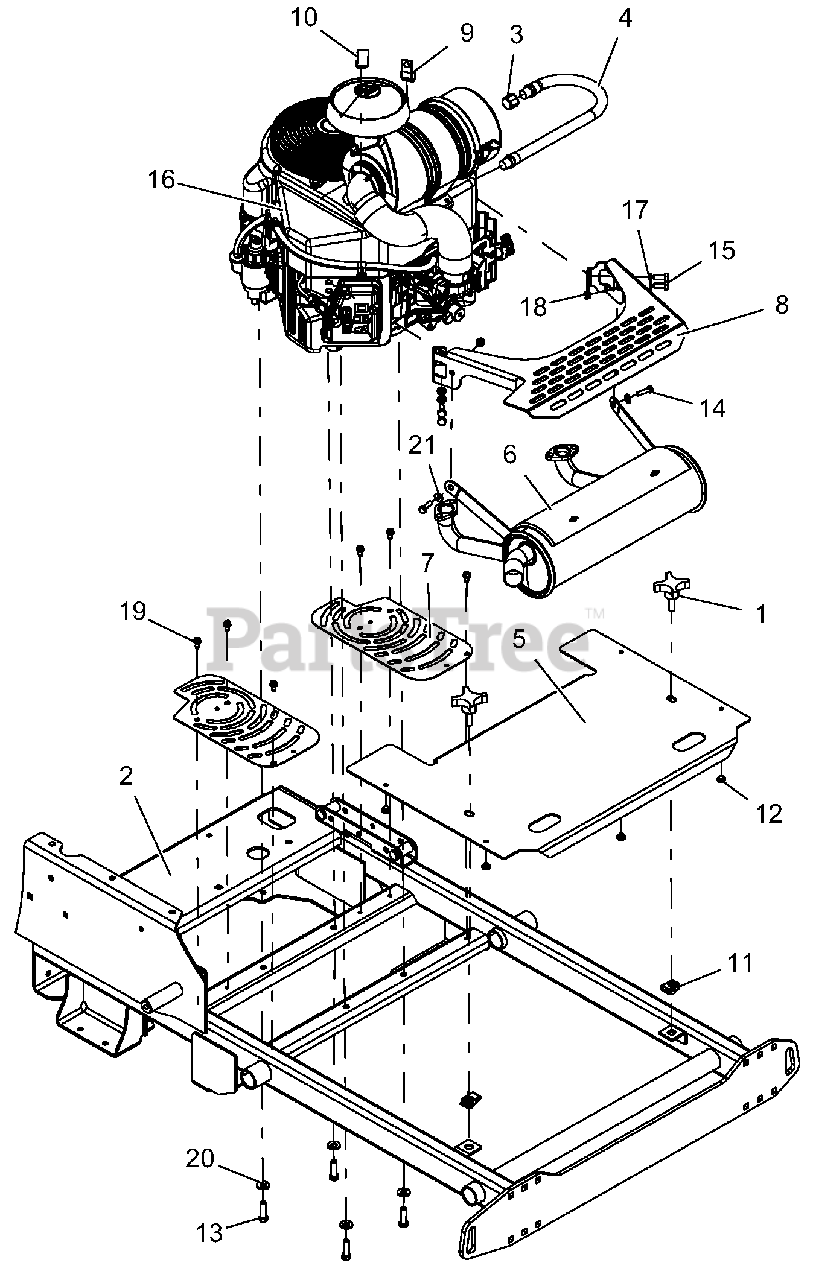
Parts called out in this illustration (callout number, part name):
1	KNOB, 3/8 x 1.25 - 4 PRONG
2	WLDMT, FRAME PROSTANCE
3	PIPE, CAP 3/8 NPT FEMALE
4	DRAIN, M20 OIL
5	SHIELD, FRONT PRO-STANCE - RED
6	EXHAUST, KAWASAKI PROSTANCE
7	GUARD, FAN
8	SHIELD, MUFFLER - BLACK
10	CLAMP, CUSHIONED STEEL REV
11	NUT, RTNR .375-16 x .37
12	BUMPER GROMMET .125 x .25 REV
13	BLT-HEX .38-16 x 1.25 GR5 YWZC NYTORQ
14	BLT-HEX .25-20 x 1.00 GR5 YWZC
15	@BLT-HEX M8-1.25 x 20 YWZC
16	ENGINE, KAWASAKI FX691
17	WSHR-LK .31 x .078 REG YWZC
18	NUT-LK-NYL-FLG .25-20 YWZC
19	SCR-TAP .25-20 x .50 HWH TR YWZ
20	WSHR, 3/8" SPRING DISC
21	WSHR-FL-STL .281 x .62 x .065 YWZC
